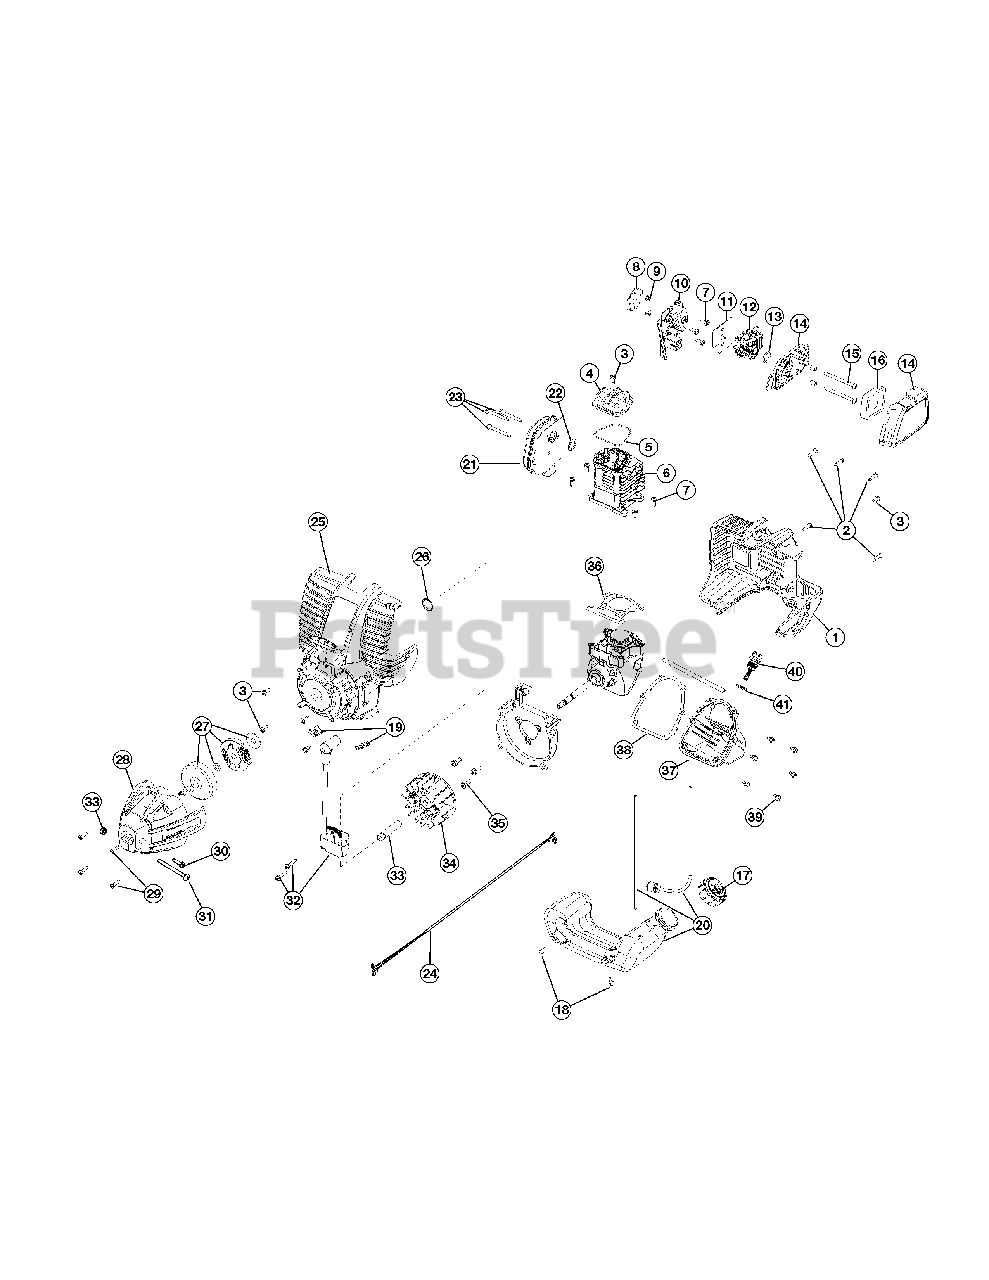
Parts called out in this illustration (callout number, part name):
1	Engine Cover
4	Valve Cover
5	Valve Cover Gasket
6	Cylinder Assembly (includes 5, 7 & 36)
7	Cylinder Screw
8	Insulator Gasket
10	Insulator (includes 11)
11	Carburetor Gasket
12	Carburetor w/Primer
13	Carburetor O-Ring
14	Air Filter Cover Assembly (includes 16)
15	Air Filter Mounting Screw
16	Air Filter
17	Fuel Cap
19	Clip Nut
20	Fuel Tank Assembly (includes 17)
21	Muffler Assembly (includes 22 & 23)
22	Muffler Gasket
23	Muffler Mounting Screw
24	Lead Wire
25	Starter Housing Assembly (includes 3)
26	Push Nut
27	Clutch Assembly
28	Clutch Cover Assembly (includes 29-31)
29	Cover Screw
30	Anti-Rotation Screw
31	Clamping Screw Assembly
32	Ignition Module Assembly
33	Spacer
34	Flywheel
35	Shroud Screw
36	Cylinder Gasket
37	Oil Pan (includes 38 & 39)
38	Oil Pan Gasket
39	Oil Pan Screw
40	Dipstick Assembly (includes 41)
